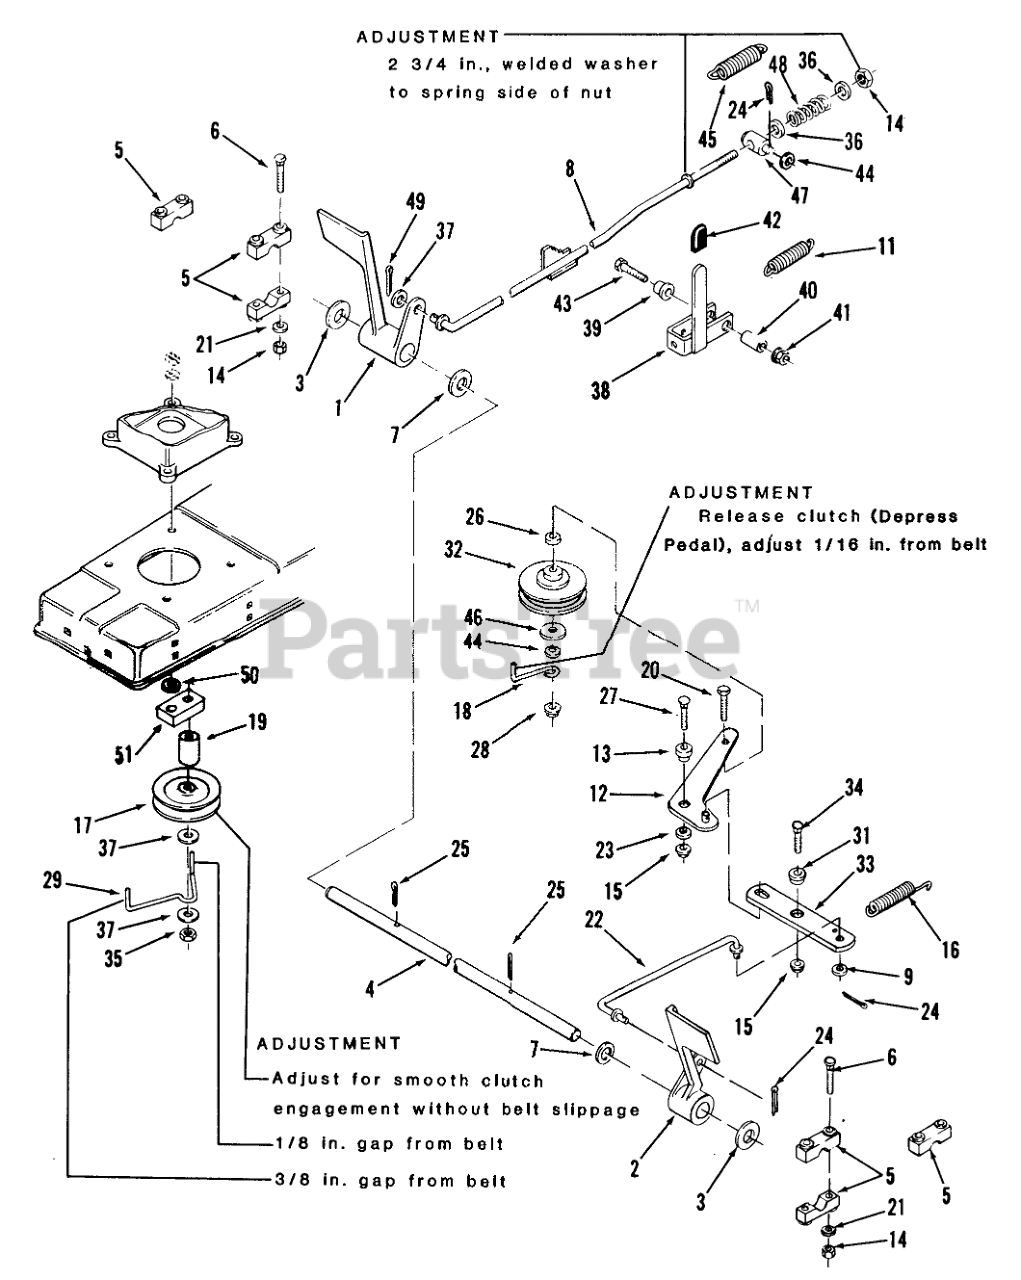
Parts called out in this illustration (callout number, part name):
1	PEDAL-BRAKE R
2	PEDAL CLUTCH R
3	Special Washer
4	SHAFT PEDAL R
5	BLOCK PIVOT
6	Washer
7	Washer
8	ASSY-BRAKE ROD
9	WASHER 5/16 SAE
11	SPRING-EXTENSION
12	IDLER ARM ASSY R
13	SPACER-IDLER ARM
14	Nut
15	LOCKNUT-FLANGE
16	SPRING
17	PULLEY-IDLER STATION
18	RETAINER-BELT
19	SPACER
20	Bolt
21	WASHER 5/16 SAE
22	ROD-CLUTCH R
23	Washer
24	Pop Rivet
26	SPACER
27	Carriage Bolt
28	LOCKNUT-FLANGE
29	RETAINER-BELT
31	SPACER
32	IDLER PULLEY
33	BAR-CLUTCH
34	Bolt
35	NUT
36	Collar
37	Washer
38	PAWL & HANDLE ASSY
39	SPACER
40	SPACER
41	LOCKNUT-FLANGE
42	GRIP
43	Bolt
44	Washer
45	SPRING-EXTENSION
46	WASHER
47	TRUNNION-LIFT
48	SPRING FRICTION
49	Cotter Pin
50	Washer-Lock
51	BLOCK-SPACER
